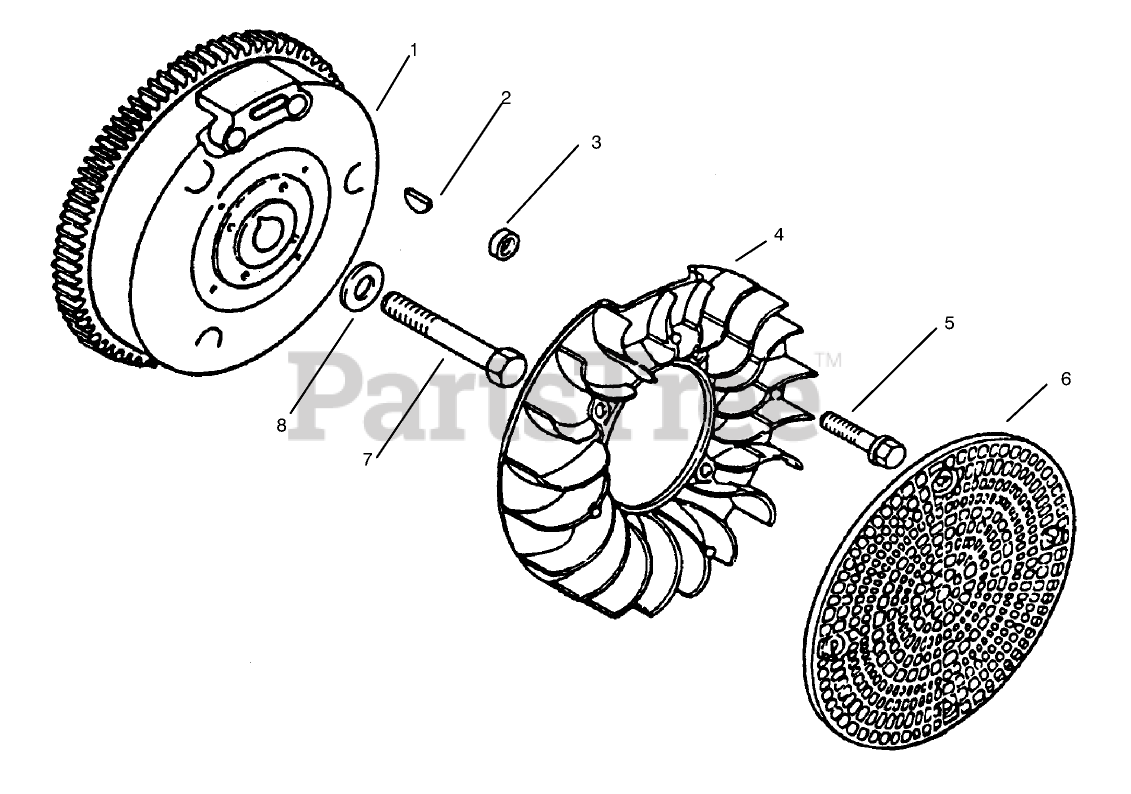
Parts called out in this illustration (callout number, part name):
1	Flywheel
2	Key-Woodruff
5	Screw-Hex Hd
